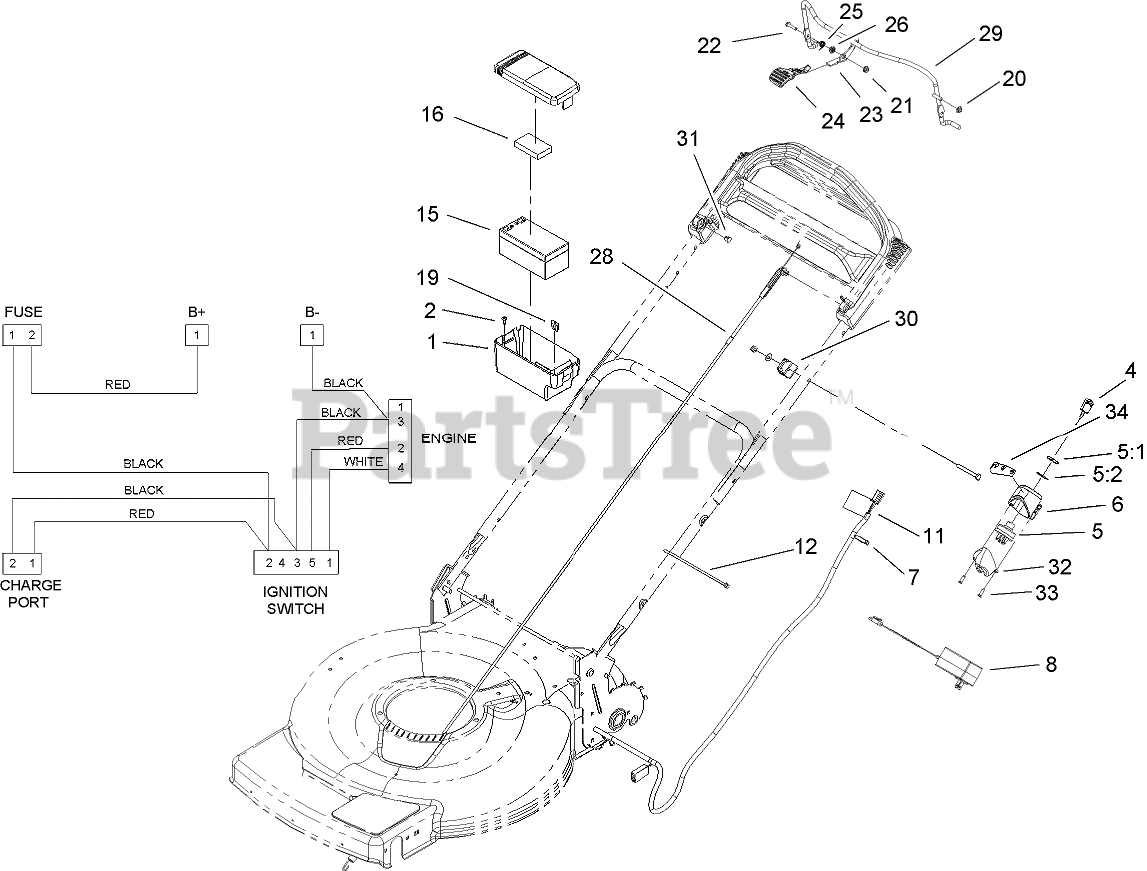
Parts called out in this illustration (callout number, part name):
1	BATTERY BOX ASM
2	SCREW-FORMING, THREAD
5	SWITCH-STARTER
5:1	NUT-HH
5:2	WASHER-TOOTH, INTERNAL
6	HOUSING-SWITCH, KEY
7	HARNESS-WIRE
8	CHARGER-12 VOLT
11	DECAL-WARNING
12	TIE-CABLE
15	BATTERY-WET
16	FOAM-BATTERY, TOP
19	FUSE-40 AMP
20	NUT-SPEED
21	NUT-LOCK, FLANGE
22	SCREW-HWH
23	LEVER
25	SPRING-TORSION
26	SPACER
28	CABLE ASM
29	BAIL-BRAKE
30	ANCHOR-CABLE, UPPER
31	Plug-Dome
32	COVER-SWTCH
33	SCREW-PPH
34	DECAL-SWITCH, IGNITION
